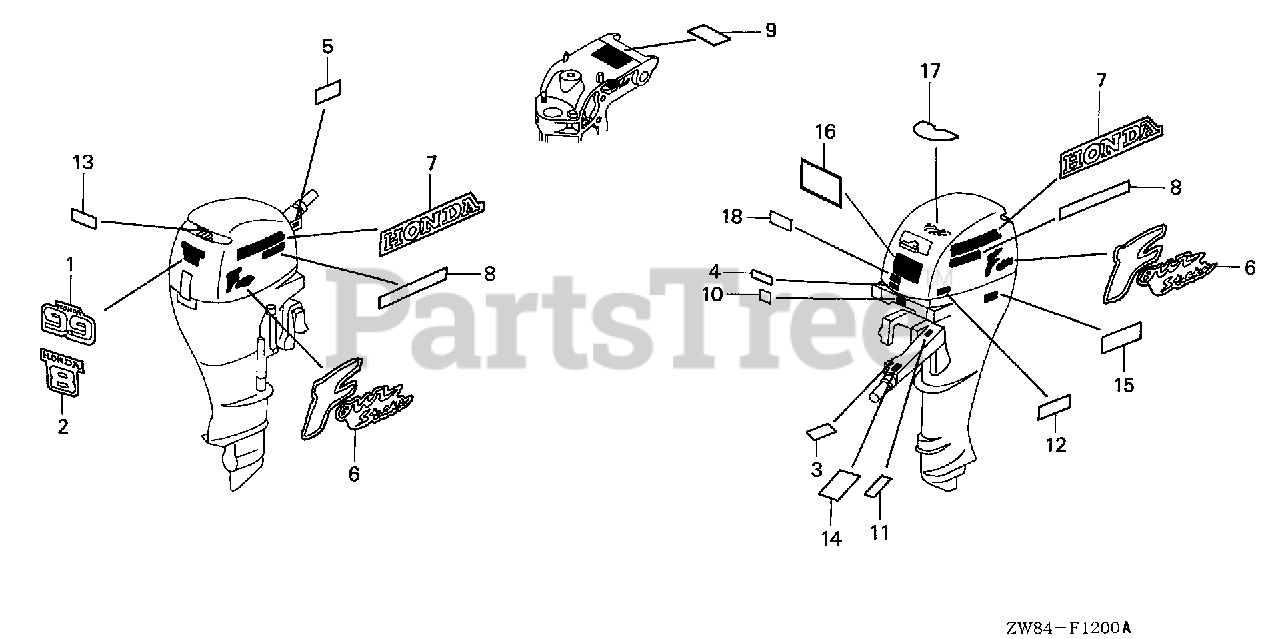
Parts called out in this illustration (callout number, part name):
1	MARK, RR. (9.9)
3	MARK, EMERGENCY SWITCH INDICATION
4	MARK, SPARE CLIP (ENGLISH)
6	MARK, SIDE
7	MARK, SIDE STRIPE
8	MARK, POWER THRUST
9	LABEL, SPECIFICATION
10	MARK, OIL PRESSURE
11	MARK, CHANGE (JAPANESE/ENGLISH)
12	MARK, RECEPTACLE (6A)
13	LABEL, OIL CAUTION (ENGLISH)
14	MARK, THROTTLE (ENGLISH)
15	LABEL, STORING CAUTION (ENGLISH)
16	LABEL, CAUTION OPERATOR (ENGLISH)
17	MARK, EMERGENCY STARTER (ENGLISH)
18	MARK (E-SPEC)
